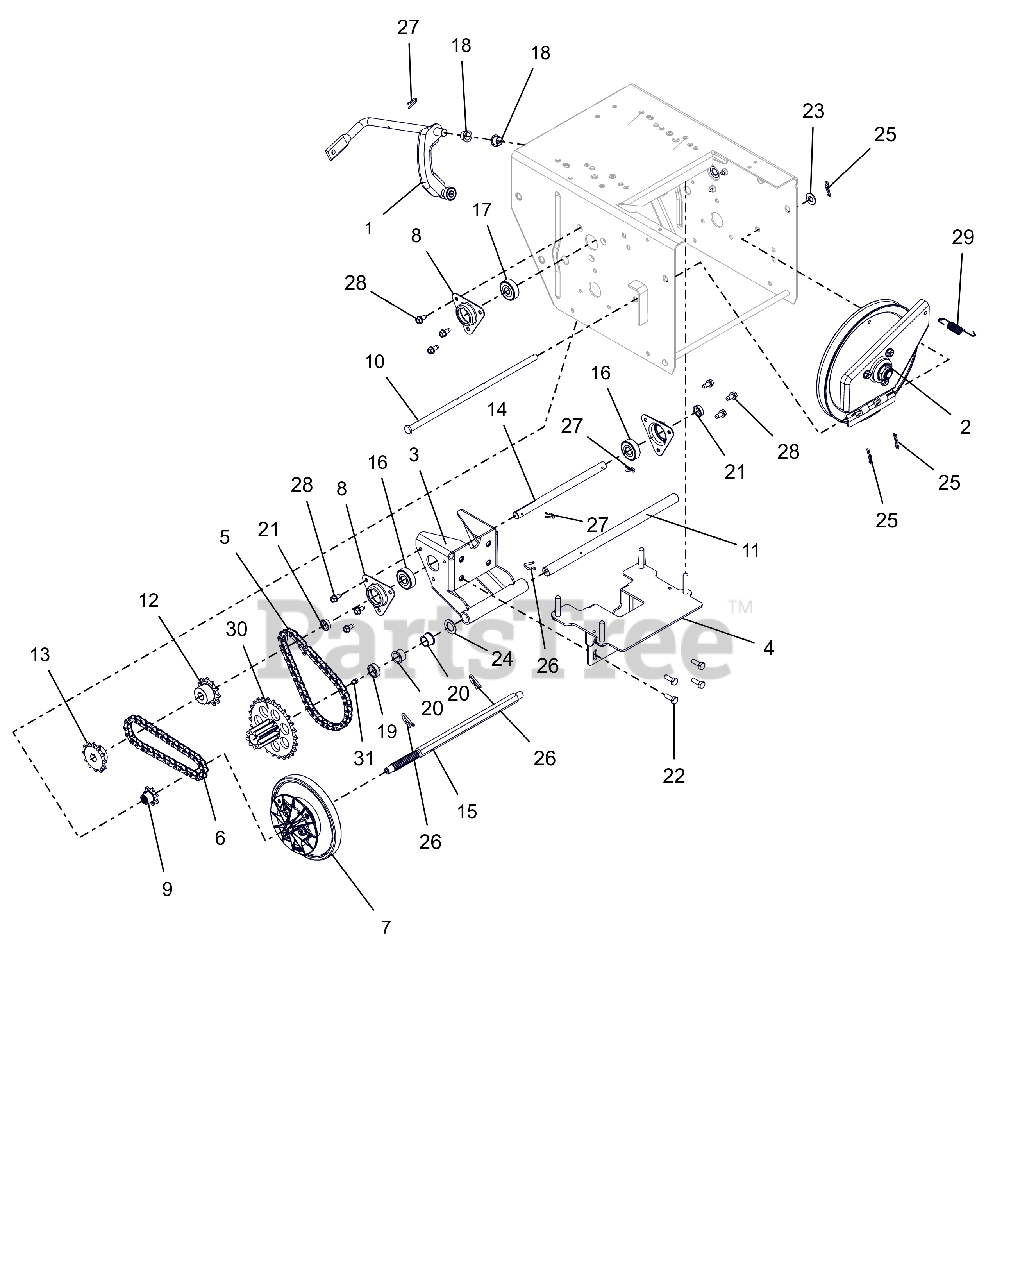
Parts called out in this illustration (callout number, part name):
1	ARM, SHIFT - ASSEMBLY
2	PLATE, SWING ASSEMBLY-DEEP
3	WLDMT, TRIPLE REDUCTION BRKT
4	STRAP, TRIPLE REDUCITON BOLT
5	CHAIN, ROLLER - #41X36 PITCHES
6	CHAIN - #41, 32 PITCHES
7	DISC, FRICTION DRIVE-ASSEMBLY
8	FLANGE, BEARING
9	SPROCKET, PINION 7T W/SPLINE
10	PIN, PIVOT
11	SHAFT, PINION-HARDENED
12	SPROCKET, 11 TOOTH
13	SPROCKET, 12 TOOTH
14	SHAFT, REDUCTION HEAT TREATED
15	SHAFT, HEX HEAT TREATED SPLINE
16	BRG-BALL .500X1.38X.437
17	BRG-BALL .437X1.375X.437
18	BUSHING, POLYLINER-.50 SPLIT
19	BSHG-SLV, .635X.880X.305
20	BSHG-FLG .625X.750X.500X.875
21	SPCR, SLV
22	BLT, HEX .25-20X.75 G5 ZCC
23	WSHR,FLT .406X.812X.065 ZCC
24	WSHR, FLT .630X1.005X.062 ZCC
25	PIN, HAIR #225 .072X1.09
26	PIN, SPRING CLIP
27	CLIP, SPRING
28	SCR-TAP .25-20X.50 HWH ZCC
29	SG-TENS .048X.50X2.8
30	PINION & SPROCKET
31	ZERK,FITTING .25X.125 DRIVE IN
